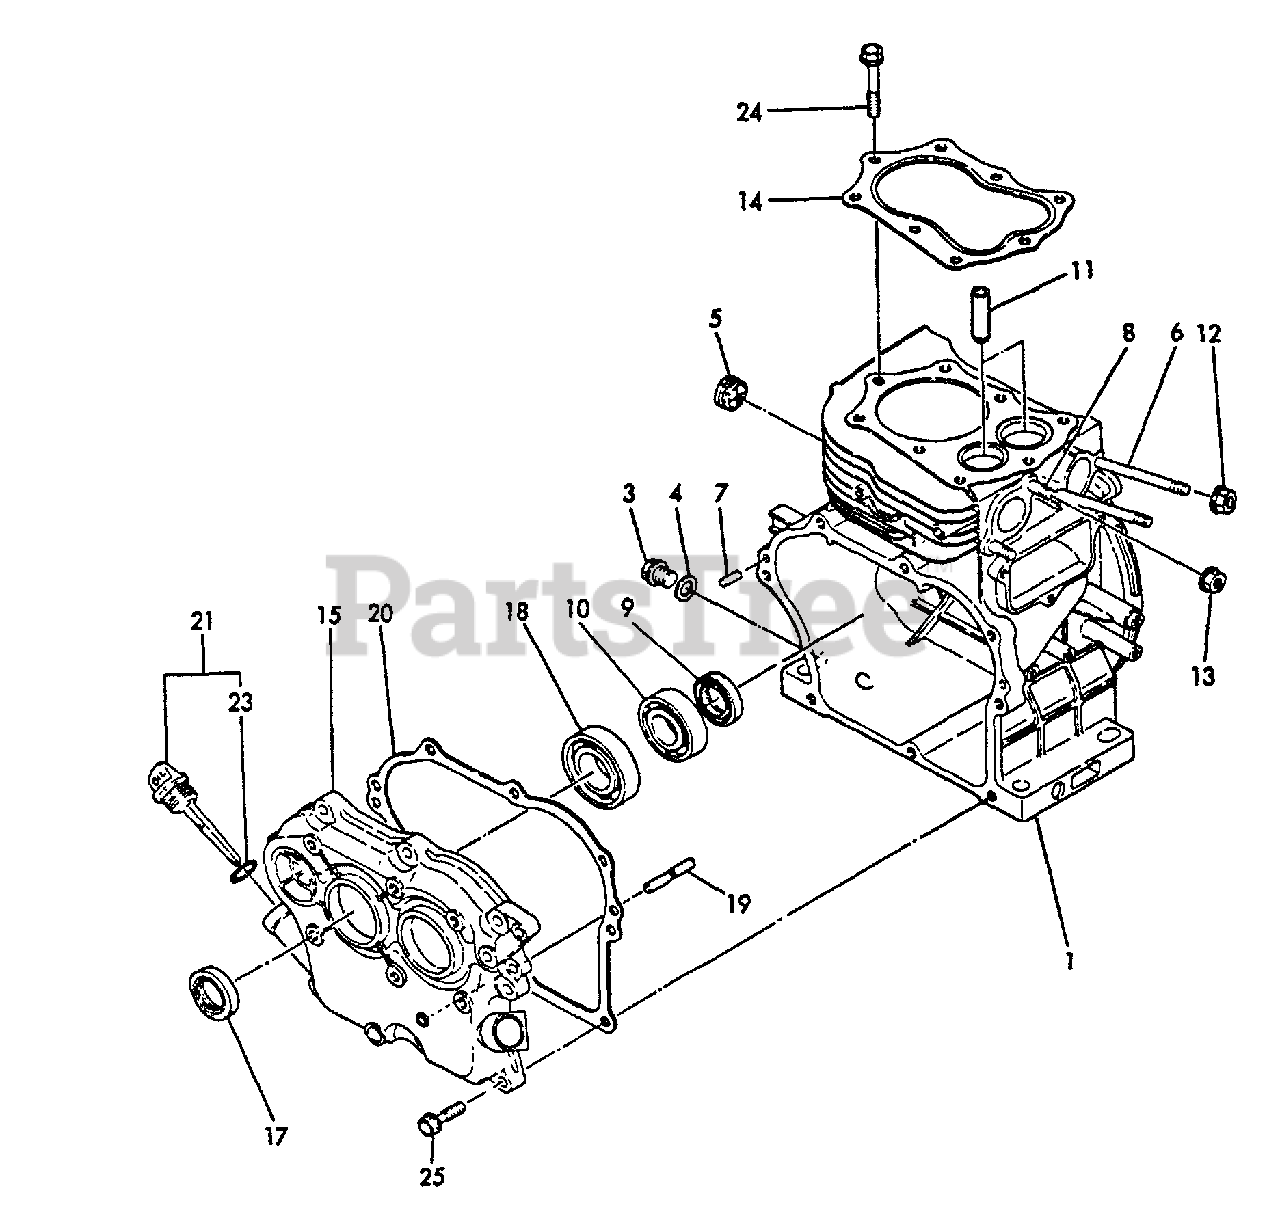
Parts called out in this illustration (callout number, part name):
1	CYLINDER BLOCK SET
3	PLUG, DRAIN
4	GASKET
5	PLUG
6	BOLT - 6×90
7	PARALLEL PIN 6×16
8	STUD - 8×18 -- PLATED
9	SEAL, OIL
10	BEARING, BALL
11	GUIDE, VALVE
12	U-NUT M6
13	U-NUT M8
14	GASKET, CYLINDER
15	SIDE COVER ASSY
17	SEAL, OIL
18	BEARING, BALL 6206C4
19	SHAFT, GOVERNOR
20	GASKET, SIDE COVER
21	CAP ASSY
23	O-RING 1A P-18.0
24	BOLT - 8×50
25	BOLT - 8×30 -- PLATED
